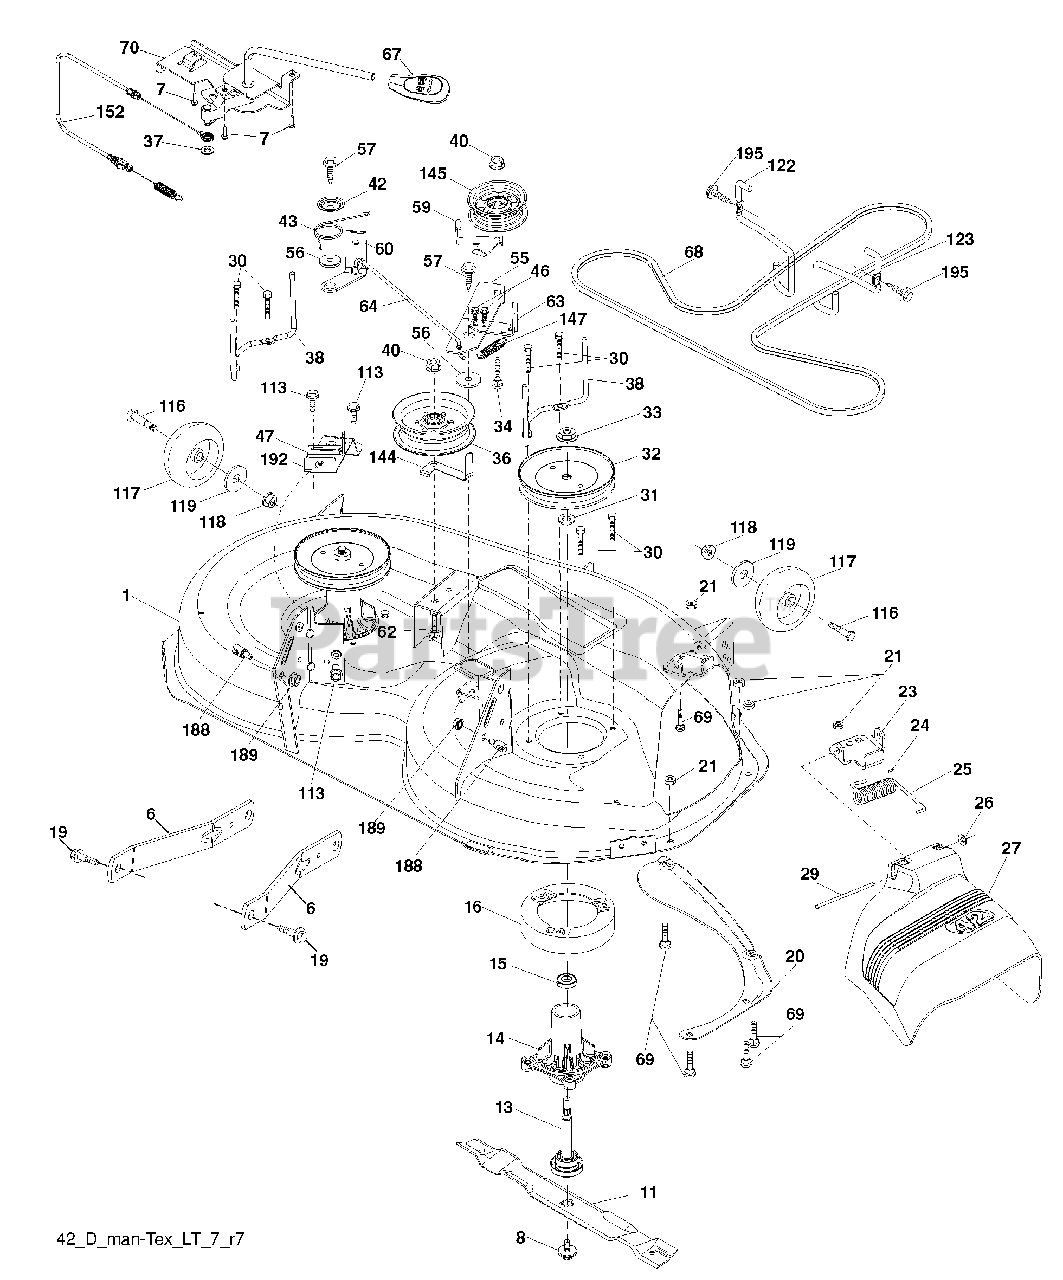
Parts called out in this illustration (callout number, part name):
6	Arm Suspension
7	Screw 10 x 3/4 Single Hex
8	Bolt/Washer asm 7/16-20 unf
8	Blade, 42" Mulching Premium(For better wear when mulching)
11	Blade, 42" Hi-Lift(For bagging or discharge)
11	Blade, 42" Mulching Std (For mulching mowers only
13	Shaft Assembly, Mandrel
14	Housing, Mandrel
15	Bearing, Ball, Mandrel
16	Stripper, Mower Deck
19	Bolt, Shoulder
20	Baffle, Vortex
21	Nut, Crownlock 5/16-18 unc
23	Bracket, Deflector
24	Cap, Sleeve
25	Spring, Torsion, Deflector
26	Nut, Push
27	Shield, Deflector
29	Rod, Hinge
30	Screw Thdrol Rolling Wsh Hd
31	Washer, Spacer
32	Pulley, Mandrel
33	Nut, Toplock, Flanged
34	Bolt Carr Sh. 3/8-16 x 1-1/2 Gr. 5
36	Pulley, Idler, Flat
37	Washer 13/32 x 13/16 x 16 Ga.
38	Keeper Belt LH Mandrel
40	Nut, Lock Flg. 3/8-16 unc
42	Spring Torsion Brake
43	Spring Torsion Retainer
46	Screw Thd Roll 1/4-20 x 5/8
47	Bracket Clutch Cable
55	Arm, Idler
56	Spacer, Retainer
57	Screw Hexwsh Thd 3/8-16 x 1
59	Guard, Tuv Idler (94)
60	Arm Brake Mower
62	Bolt Rdhd Sqnk 3/8-16 unc x 2
63	Arm Brake Mower
64	Linkage Brake
67	Handle, Clutch Cable
68	V-Belt
69	Bolt Rdhd Sqnk 5/16-18 x 5/8
70	Clutch Asm. Manual
113	Screw 5/16-18
116	Bolt
117	Wheel Gauge
118	Nut Lock 3/8-16 UNC
119	Washer 3/8-7/8 x 14 Ga.
122	Keeper Belt Eng. LH
123	Keeper Belt Eng. RH
144	Keeper Belt
145	Pulley Idler
147	Spring Return
152	Cable Clutch Manual w/Spr.
188	Stud Fastener
189	Nut Lock Hex Flange
192	Bracket Brake Stand LH
195	Screw Hexwsh Thdr 3/8-16 x 3/4
195	Mandrel Assembly
195	Replacement Mower, Complete
